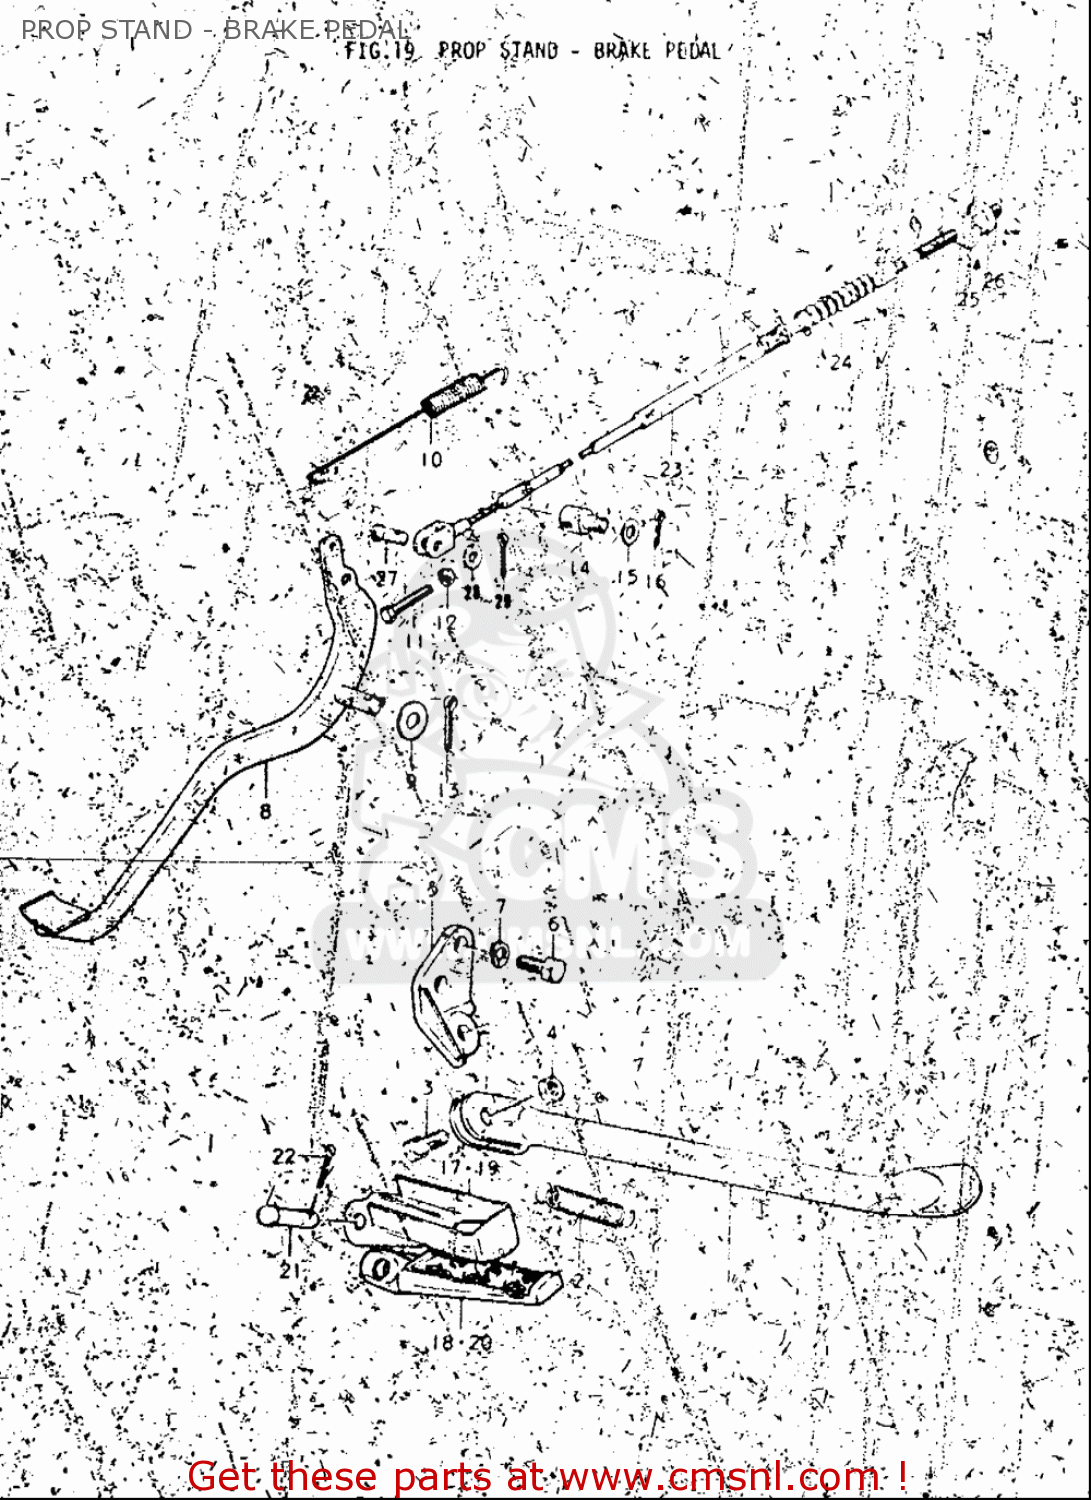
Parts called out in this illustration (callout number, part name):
2	SPRING
3	BOLT(10X30)
4	NUT
6	BOLT
7	WASHER,LOCK
9	WASHER (10.5X24X2.3)
12	NUT
13	PIN 30X20
16	PIN
19	FOOTREST,FRONT,LEFT
22	PIN
23	CABLE,RR BRAKE
24	SEAL,DUST
25	PIN(13X18)
26	NUT
27	PIN(L:13.5)
28	WASHER
29	PIN
